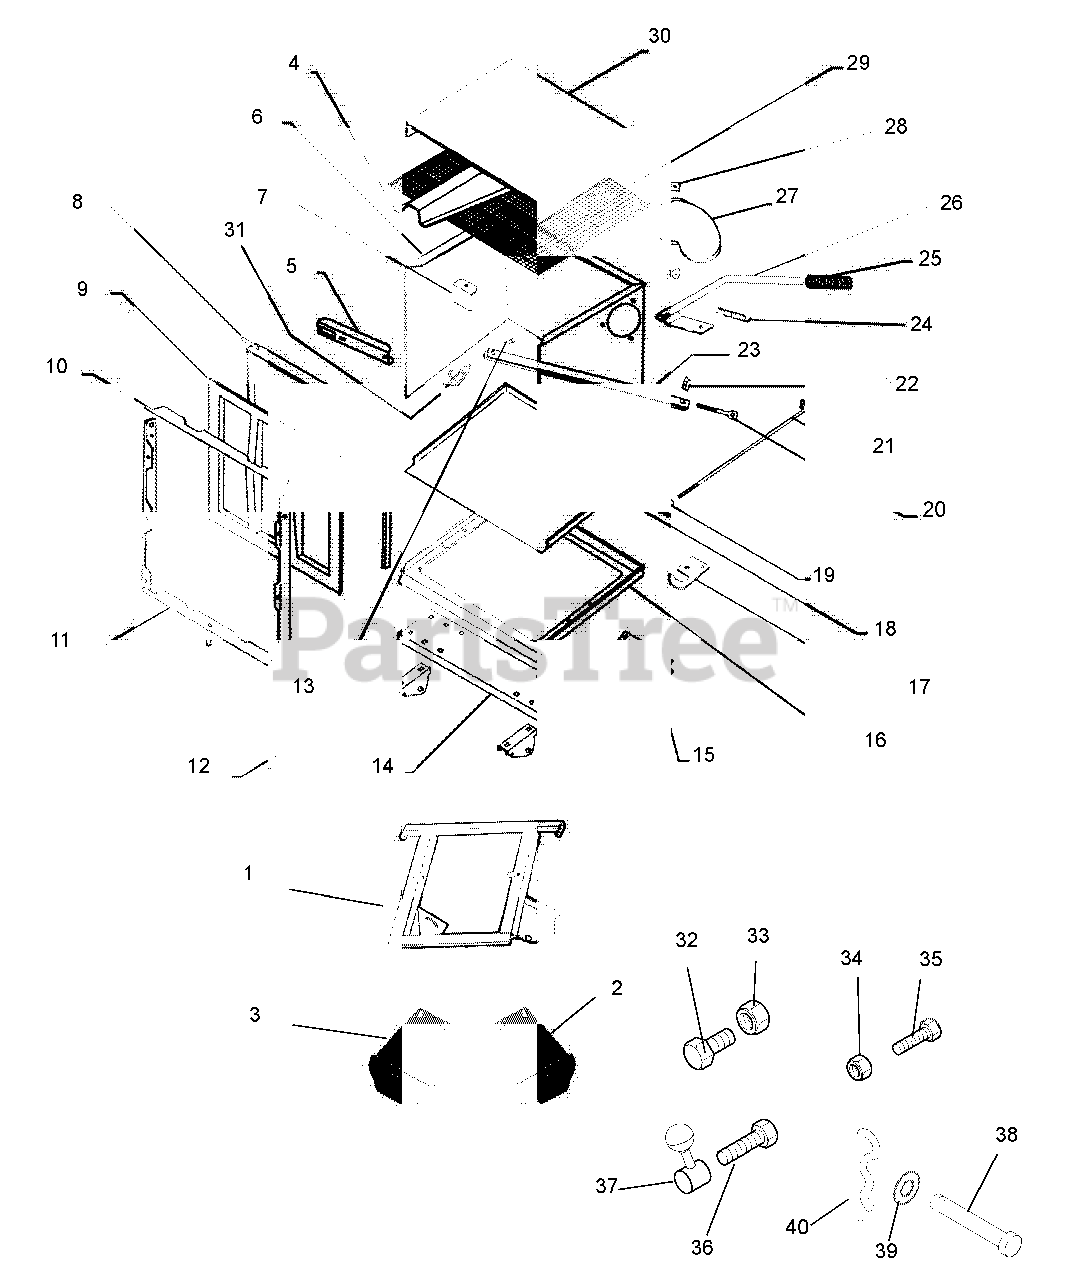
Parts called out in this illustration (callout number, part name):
1	Frame, Top Main
2	Frame, Main Left Leg
3	Frame, Main Right Leg
4	Screen Support
5	Handle Mount
6	Box Back and Sides
7	Fill Gauge
8	Box Door/Frame
9	Plastic Door
10	Upper Door Member
11	Door Frame Assembly
12	Pivot Bracket
13	Linkage Pin
14	Base Frame Pivot Mount
15	Latch Hook Plate
16	Base Frame
17	Latch Hook
18	Box Bottom
19	Ball Joint
20	Adjusting Screw
21	Latch Rod
22	Nut, Adjusting
23	Rod, Linkage
24	Spring, Latch
25	Grip, Handle
26	Handle, Box
28	Clamp, Inlet
30	Box Top, Aluminum
31	Rue-Lock Pins
32	Bolt, Hex .75-10 x 1.50 Grade
33	Nut, Lock .75-10
34	Nut, Nylon Lock .375-16
35	Bolt, Hex .375-16 x 3.0 Grade 5
36	Bolt, Hex .50-13 x 1 Grade 5
37	Handle, Pivot Frame
38	Pin, Detent .625 x 3.00
39	Washer Flat Steel .656 x 1.31 .095
40	Pin, Hair .156 x 2.625
